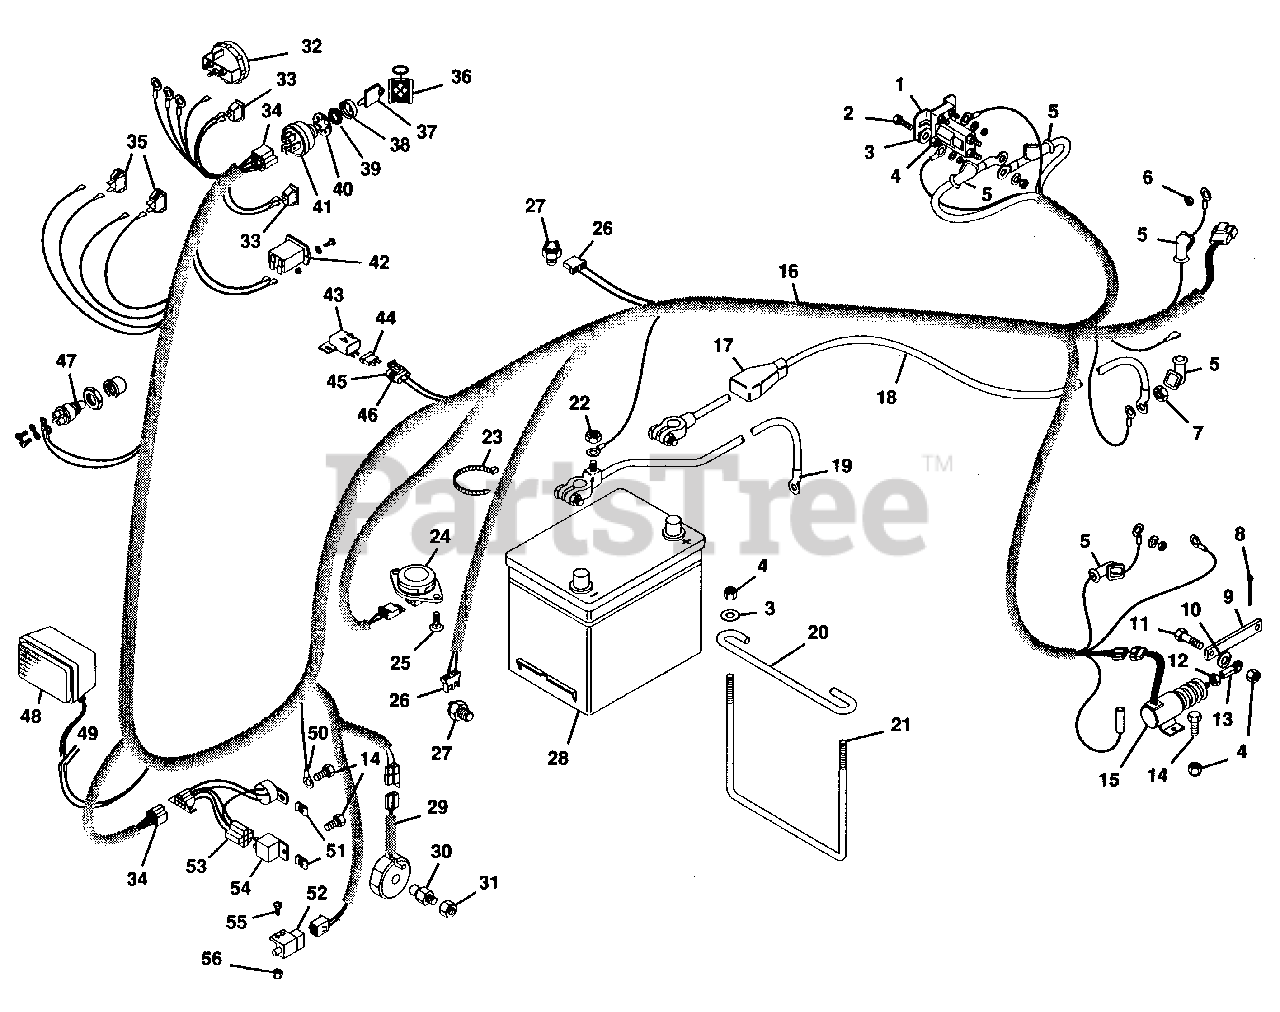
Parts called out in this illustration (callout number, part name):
1	Switch, Magnetic
2	Bolt, Hex 1/4-20x.75
3	Washer, Flat .281x.625x.065
4	Nut, Lock 1/4-20
5	Boot, Battery Cable
6	Nut, Hex M5x.8
7	Nut, Hex M8x1.25
8	Pin, Cotter .06x.75
9	Plate, Stop
10	Washer, Lock 1/4 Reg.
11	Bolt, Hex 1/4-20x1.00
12	Nut, Jam 1/4-28 Hex
13	Rod End, Female 1/4-28
14	Bolt, Hex 1/4-20x.625
15	Solenoid, Engine Stop
16	Harness, Wiring
17	Cover, Battery Terminal
18	Cable, Positive Battery
19	Cable, Negative Battery
20	Rod, Hold Down
21	Rod, Battery
22	Nut, Hex 5/16-18
23	Tie Wrap, Black
24	Switch, Seat
25	Screw, Machine 1/4-20x.50
26	Connector, 2-Wire Switch
27	Switch, Interlock
28	Battery, 24-F
29	Assembly, Magnet
30	Pin, Magnet
31	Nut, Lock 1/2-13
32	Gauge, Water Temperature
33	Switch, Light
34	Connector
35	Light, Indicator
36	Chain, Key
37	Key, Ignition Switch
38	Boot, for 9/16 Switch Nut
39	Nut, 9/16-24 for Switch
40	Washer, Lock
41	Switch, Ignition
42	Hourmeter
43	Cover
44	Fuse, 25 Amp
45	Terminal, 14-16 Gauge
46	Connector
47	Switch, Preheater
48	Headlamp, 3 x 5 Halogen
49	Terminal, Male
50	Terminal, Ring Tongue
51	Nut, Speed 1/4-20
52	Switch, Interlock
53	Module, Time Delay
54	Relay
55	Screw, Machine 10-24x.625 PHD
56	Nut, Lock 10-24
